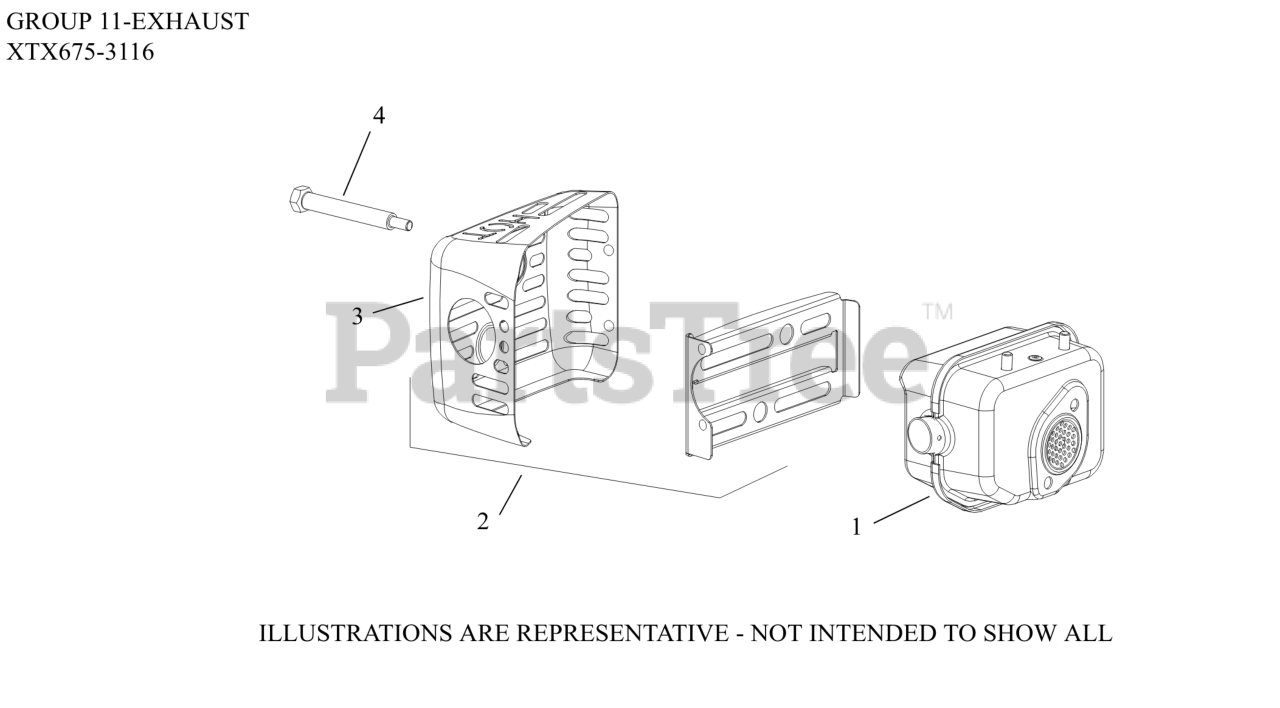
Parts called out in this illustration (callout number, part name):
1	MUFFLER, ASSEMBLY
2	GUARD, MUFFLER ASSEMBLY
3	GUARD, MUFFLER - DISCONTINUED
4	SCREW, SHOULDER
